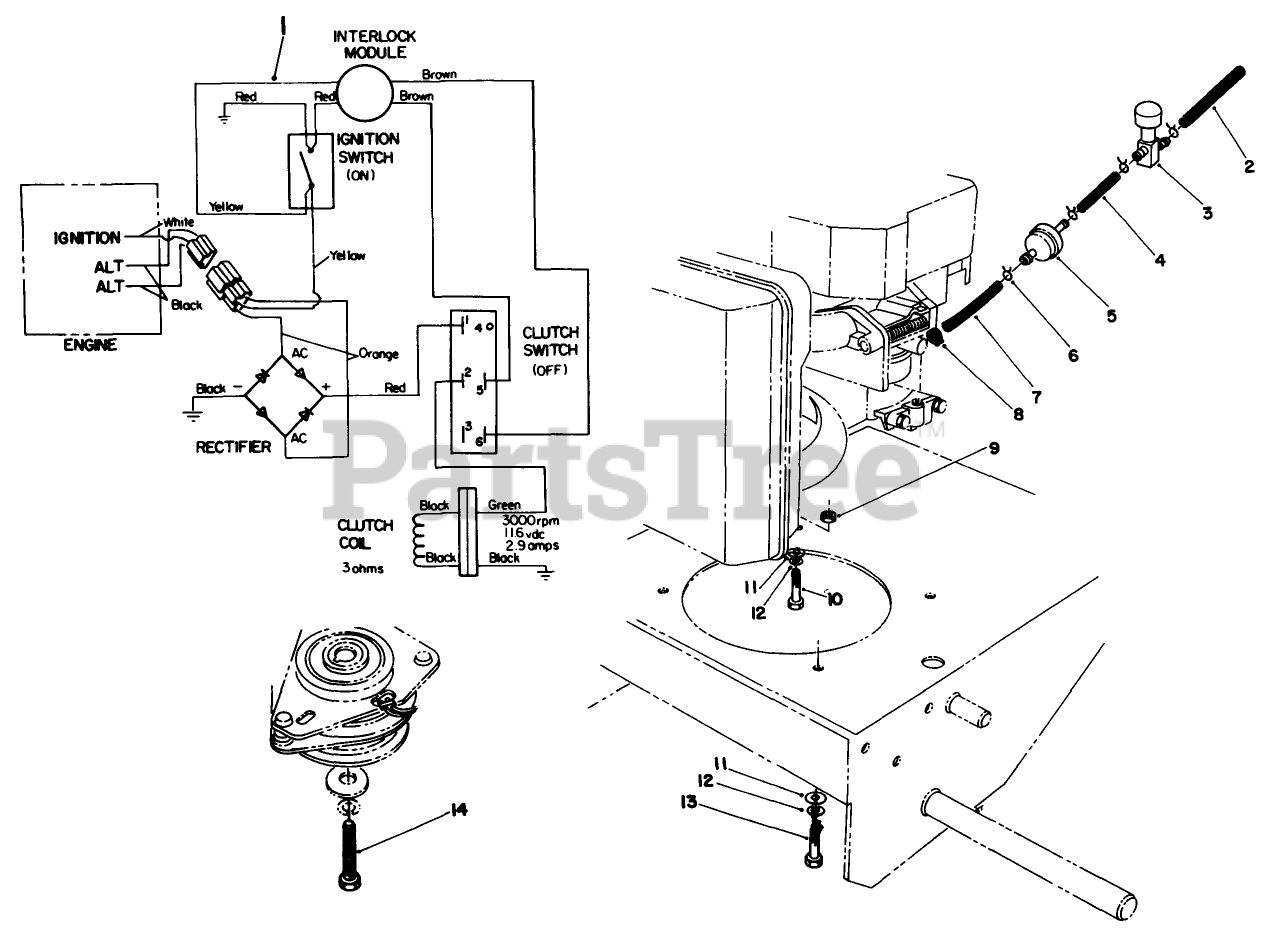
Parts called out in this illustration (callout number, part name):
5	FILTER-FUEL
8	CLAMP-HOSE
9	NUT-JAM
10	SCREW
11	WASHER-PLAIN
12	WASHER-LOCK
14	SCREW-CLUTCH
